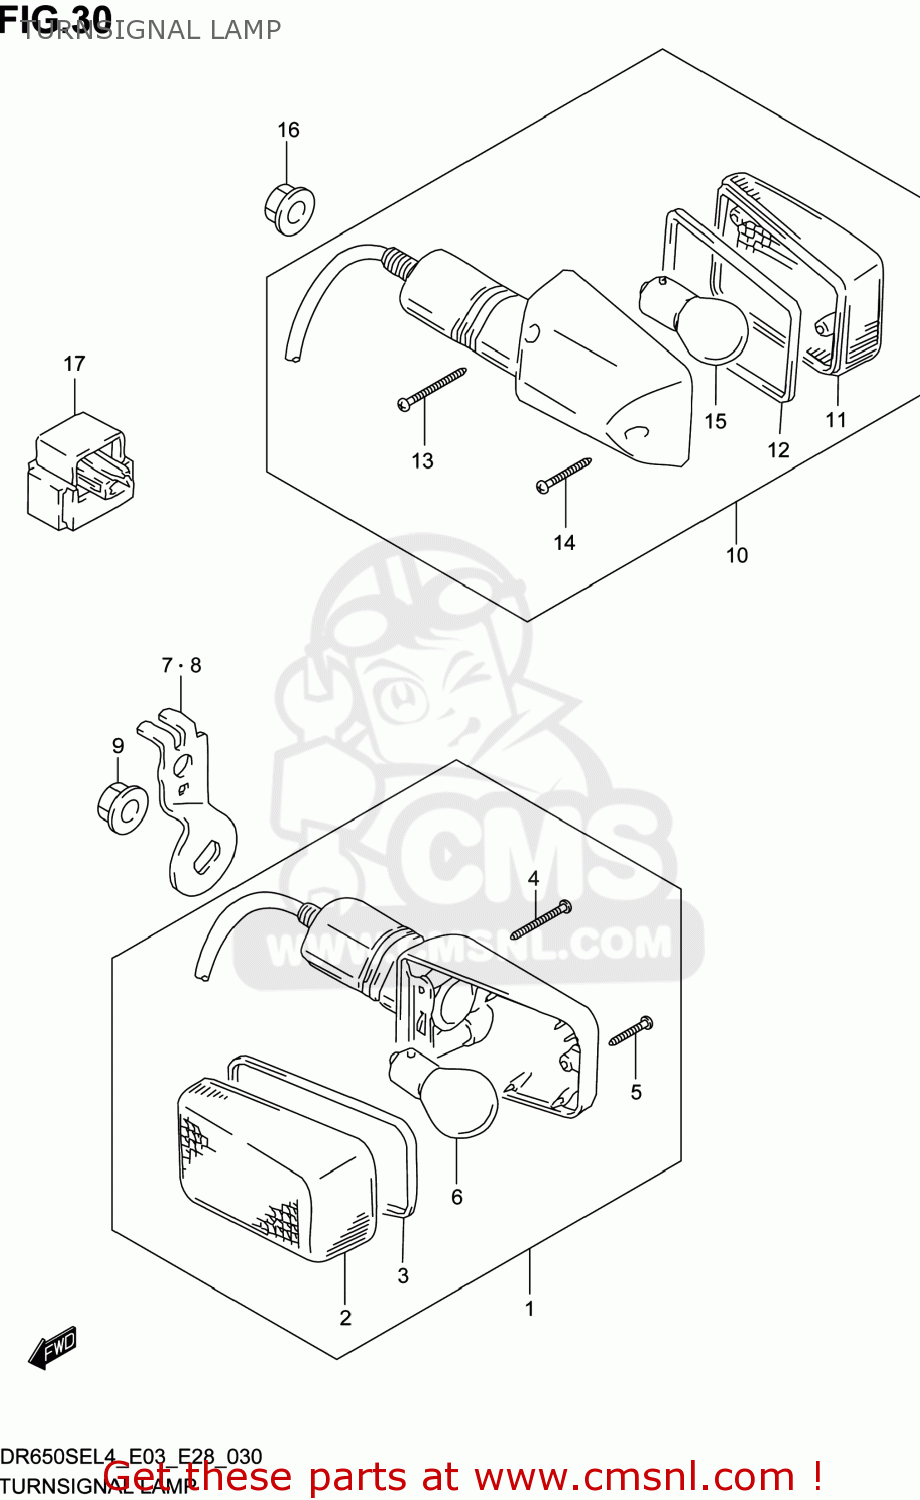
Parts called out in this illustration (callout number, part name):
1	LAMP ASSY,FR TURN SIGNAL
2	LENS
3	GASKET (NAS)
4	SCREW(3X30)
5	SCREW
6	BULB(12V21W)
7	BRACKET,FR TURNSIGNAL,R
8	BRACKET,FR TURNSIGNAL,L
9	NUT
10	LAMP ASSY,RR TURNSIGNAL,R
11	LENS
12	GASKET (NAS)
13	SCREW(3X30)
14	SCREW
15	BULB(12V21W)
16	NUT
17	RELAY ASSY
